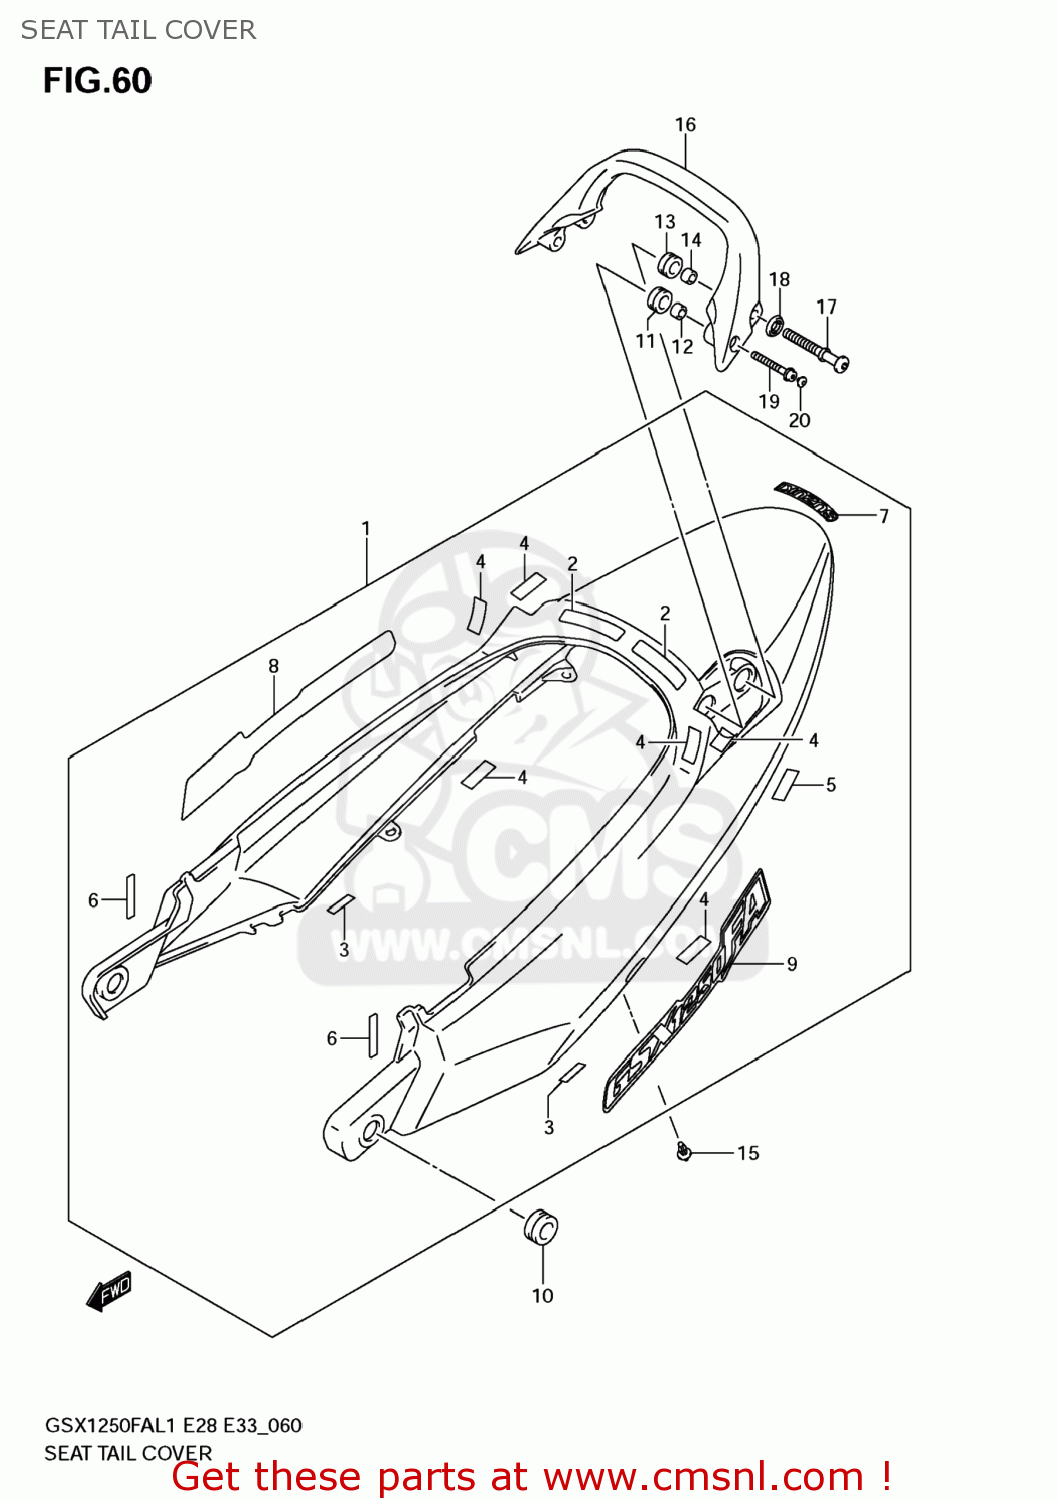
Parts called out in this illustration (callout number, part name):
1	COVER ASSY,SEAT TAIL(BLACK)
2	TAPE,COVER
3	TAPE,SEAT TAIL COVER
4	PROTECTOR,FRAME COVER
5	PROTECTOR,FRAME COVER
6	CUSHION
7	EMBLEM,SUZUKI
8	EMBLEM,SEAT TAIL COVER,R
9	EMBLEM,SEAT TAIL COVER,L
10	CUSHION
11	CUSHION
12	SPACER(6.5X12X9)
13	CUSHION
14	SPACER,8.5X14X9
15	CLIP(BLACK)
16	HANDLE. PILLION RIDER (BLACK)
17	HOOK,PILLION RIDER HANDLE
18	WASHER,HOOK
19	BOLT
20	CAP(OD:10)
